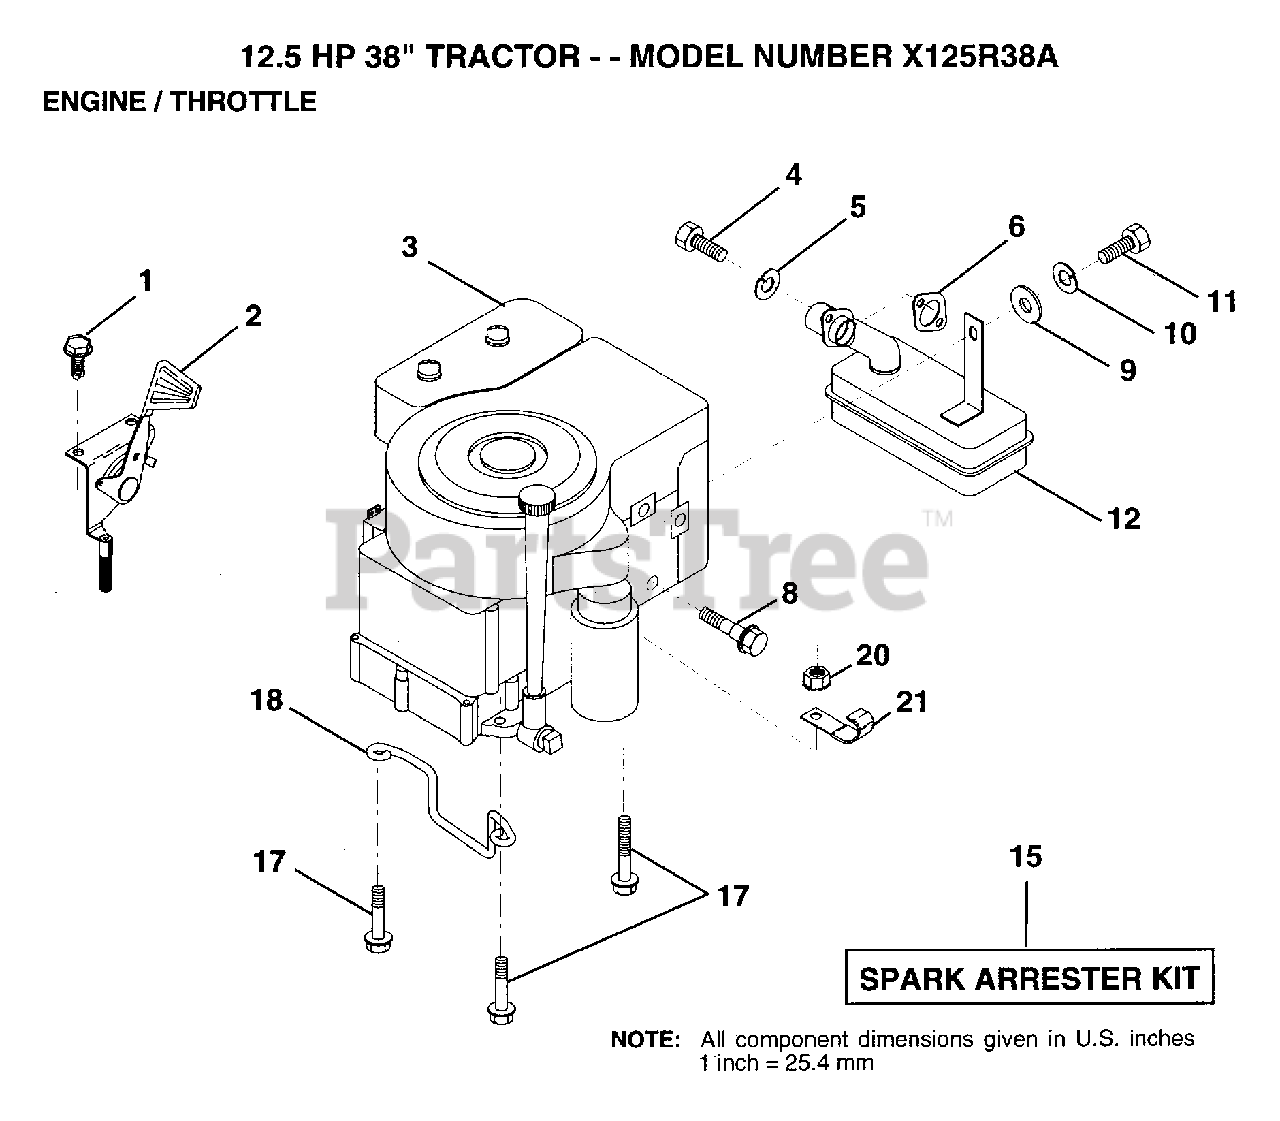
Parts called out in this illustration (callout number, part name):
1	SCREW.1/4-20X1/2
2	"CONTROL,THROTTLE"
3	ENGINE, B&S
4	SCREW
5	LOCKWASHER
8	BOLT T
10	LOCKWASHER
12	MUFFLER
17	SCREW LT
18	"KEEPER,DR BELT GR"
20	NUT
21	CLIP T
